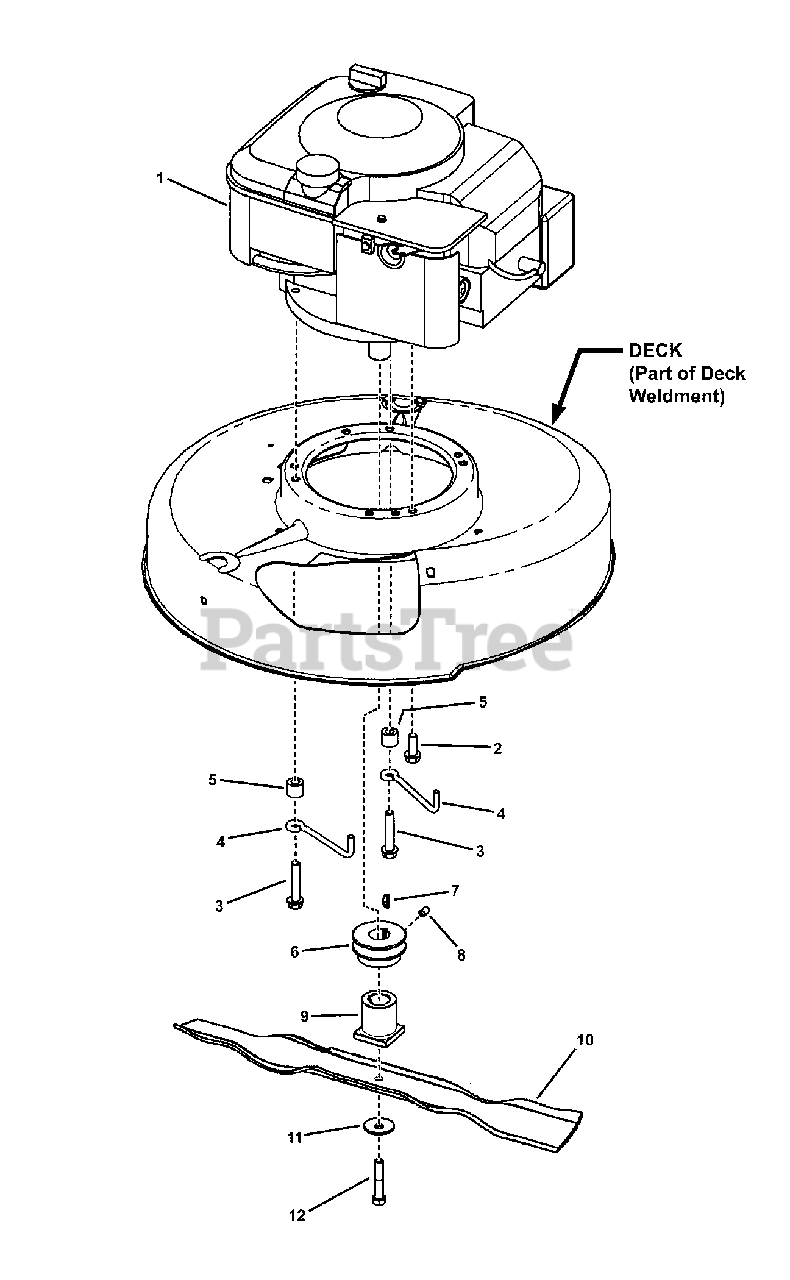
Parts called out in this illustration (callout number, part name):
2	SCREW, 3/8-16 x 1" Hex Washer Self-Tap
3	SCREW, 3/8-16 x 2" Hex Washer Self-Tap
4	GUIDE, Belt
5	SPACER, Belt Guide
6	PULLEY, Engine
7	KEY, Hi-Pro (#HP-506)
8	SET SCREW, 5/16-18 x 1/2" Hex Recess
9	HUB, Blade Drive, 25 MM I.D.
10	BLADE, Wave, 21" Steel Deck
11	WASHER, Cone
12	SCREW, 3/8-24 x 2" Hex Head Cap, GR 5
